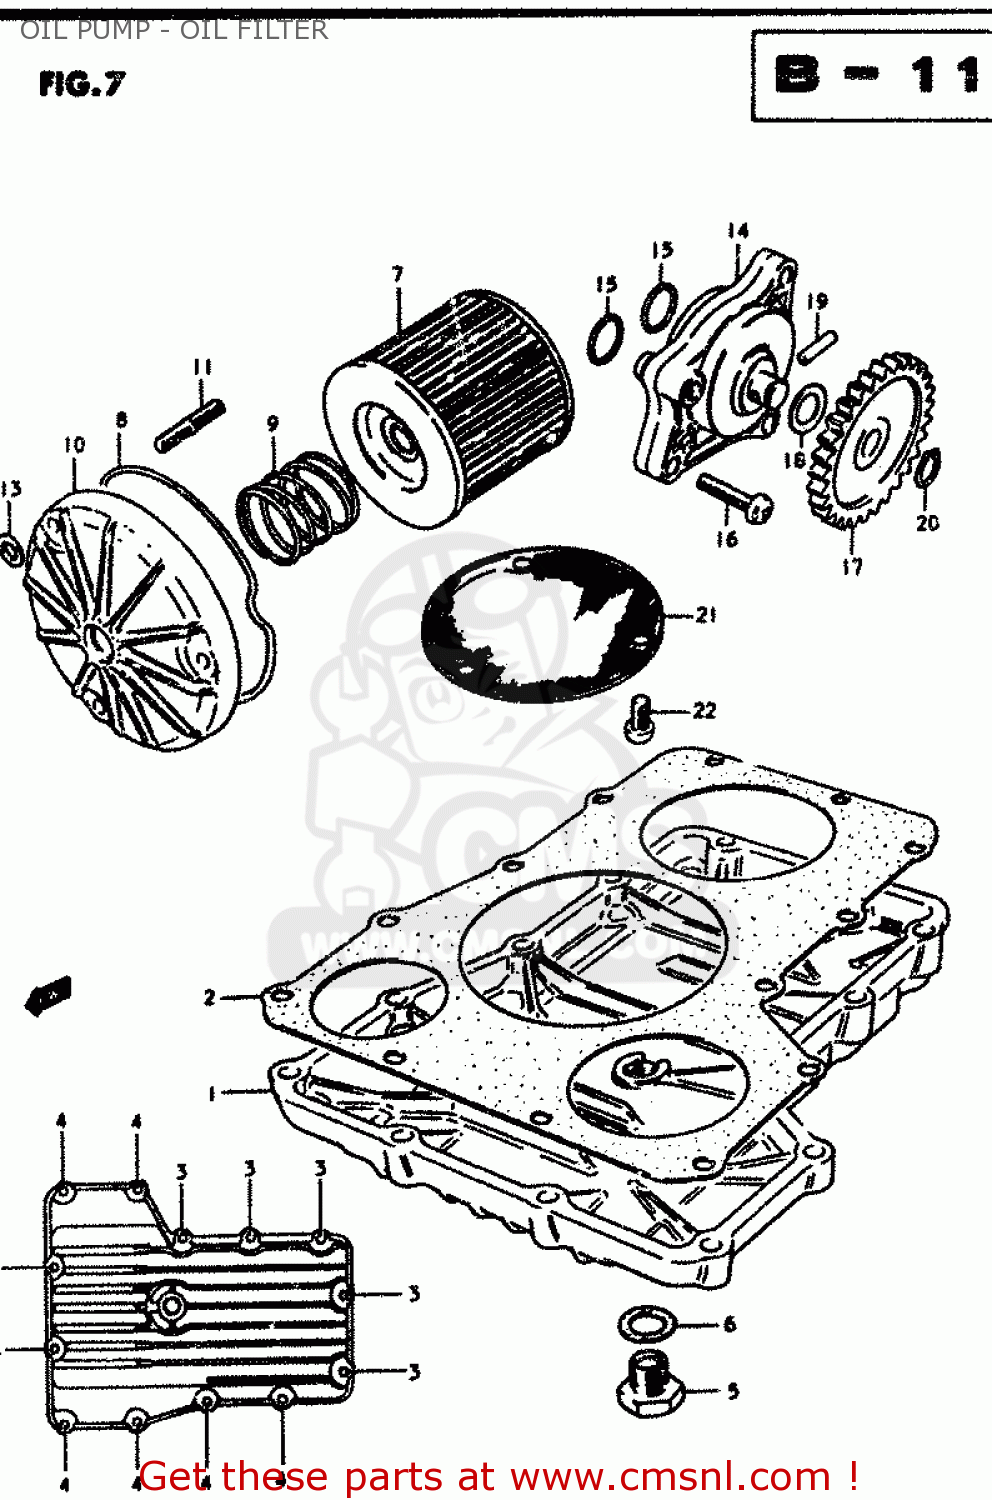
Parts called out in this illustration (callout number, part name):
1	PAN,OIL
2	GASKET,OIL PAN (MCA)
3	BOLT
4	BOLT
5	PLUG
6	GASKET(14X19.2X2) (NAS)
7	FILTER ASSY,ENGINE OIL
8	O RING,OIL FILTER CHAMBER CAP
9	SPRING
10	CAP,OIL FILTER
11	STUD 6X20
12	NUT
13	WASHER
14	PUMP ASSEMBLY,ENGINE OIL
15	O RING(D:1.9,ID:13)
16	SCREW
17	GEAR,ENG OIL PUMP DRIVEN(NT:33
18	SHIM
19	PIN(4X15.8)
20	CIRCLIP
21	STRAINER,ENGINE OIL
22	SCREW 6X12
